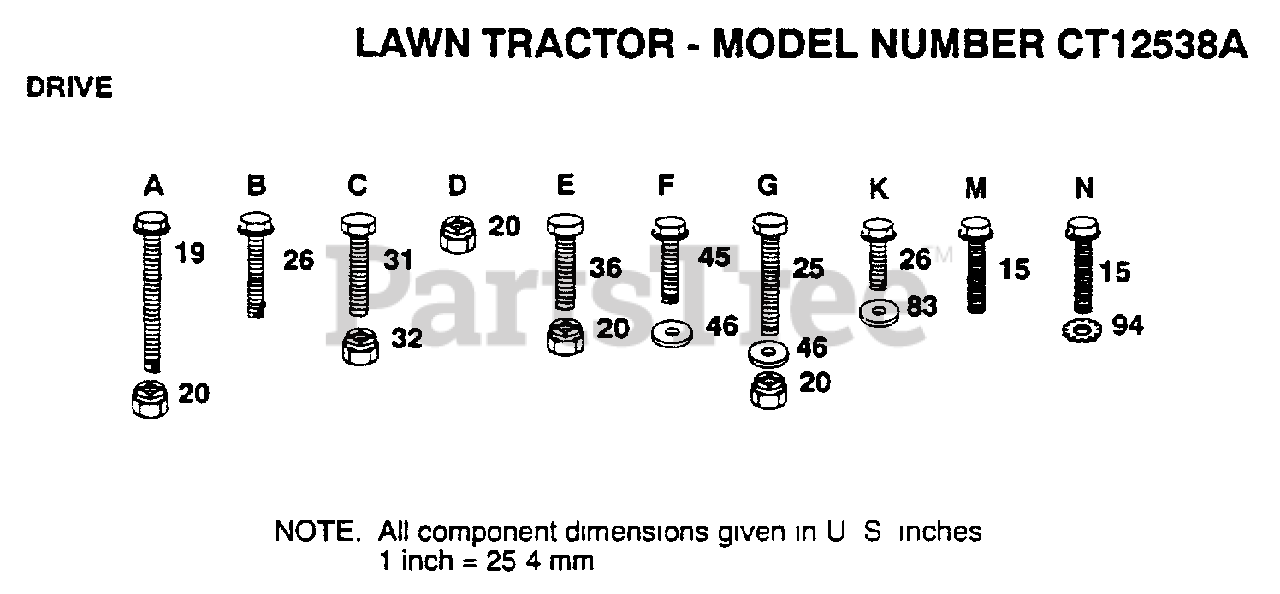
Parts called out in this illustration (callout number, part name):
15	SCREW
25	BOLT
26	SCREW
31	BOLT
45	SCREW
46	WASHER
83	WASHER
94	LOCKWASHER
